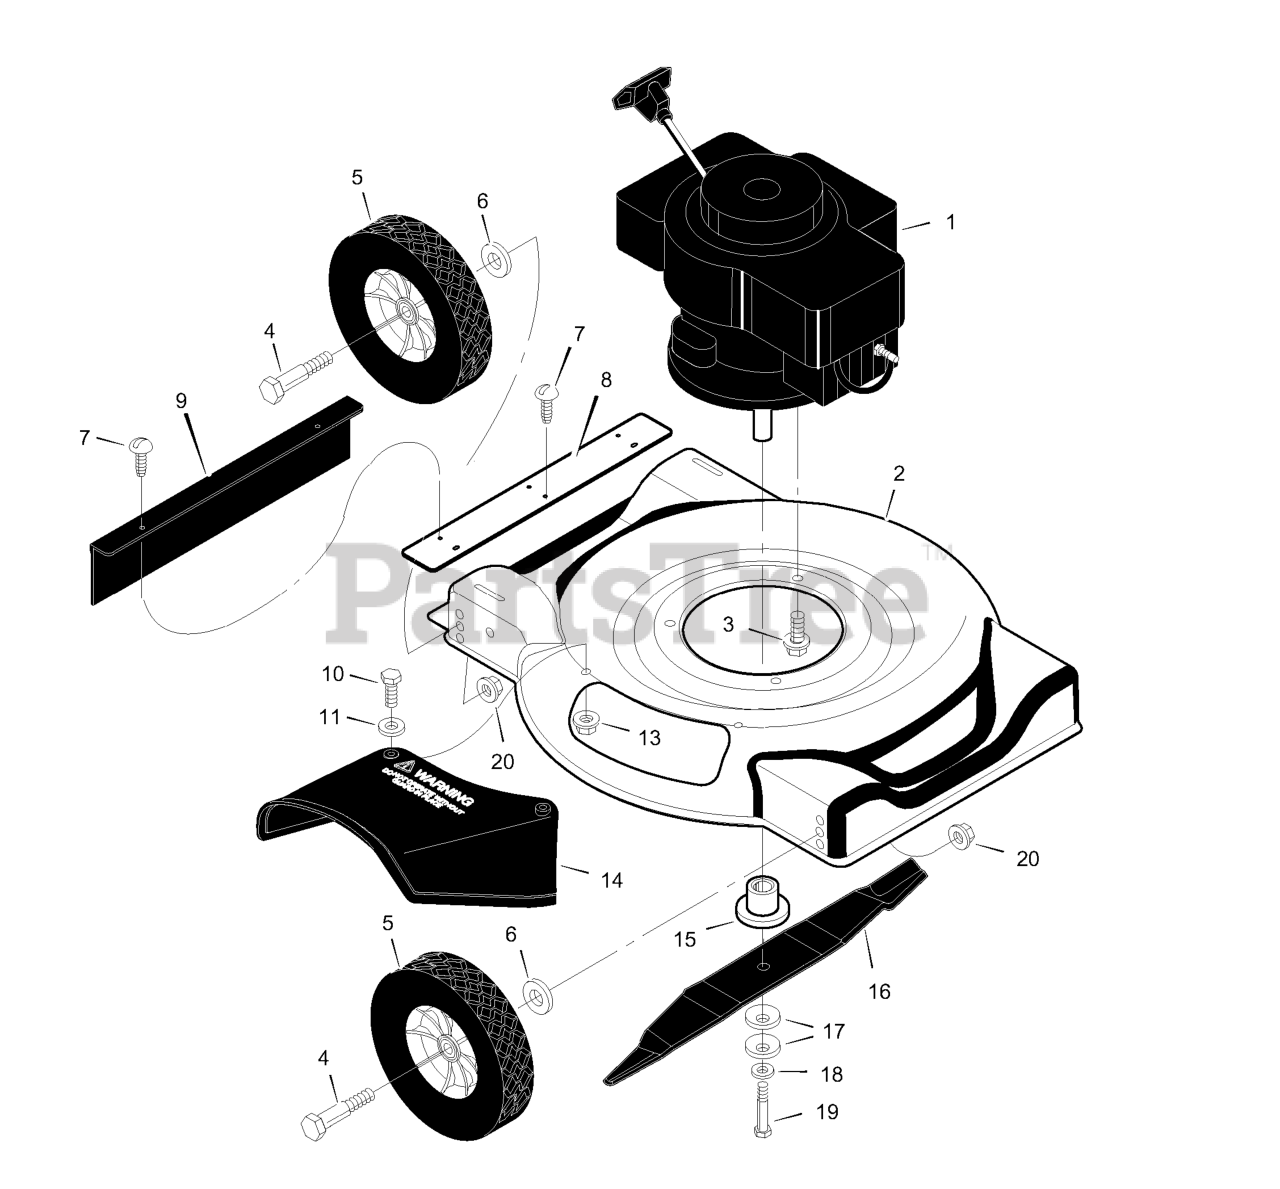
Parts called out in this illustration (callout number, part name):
1	Engine
2	Housing
3	Bolt, Engine
4	Bolt, Axle
5	Wheel and Tire
8	Extension, Rear
9	Deflector, Rear
13	Locknut
14	Deflector, Chute
15	Blade Adapter
16	Blade - 20"
17	Washer, Blade
20	Locknut
